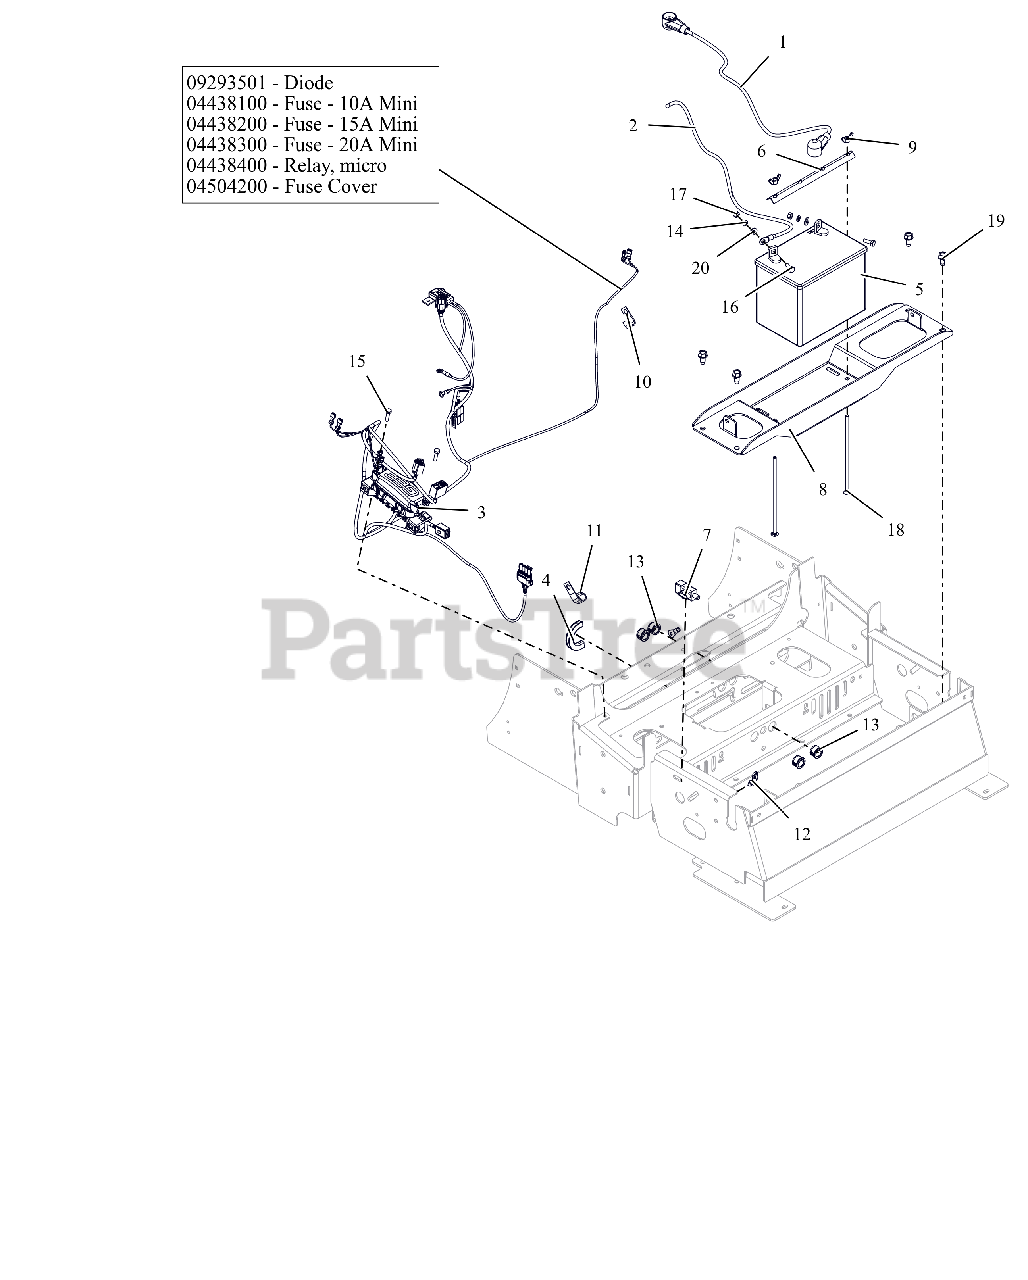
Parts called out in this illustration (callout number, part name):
1	CABLE - POS BATT W/BOOTS 6X35
2	CABLE-NEGATIVE BATTERY 35.00"
3	HARNESS, PT400 WIRING
3	DIODE, CONNECTOR SHELL
3	FUSE,10 AMP MINI-ATC
3	FUSE,15 AMP MINI-ATC
3	FUSE,20 AMP MINI ATC
3	RELAY,MICRO5 TERML W/RESISTOR
3	COVER, HARNESS FUSE/RELAY MOD
4	STRIP, COWL
5	BATTERY, 300 CCA 10U1L
6	HOLD DOWN
7	SWITCH, SNAP IN - N.O./N.O.
8	PT400 GAS BATTERY TRAY - RED
9	NUT, LK-WING .25-20 ZCC
12	CABLE TIE W/ TREE (.25 HOLE)
13	BUSH, PANEL SNAP .687X.875X.56
14	WSHR,LK-REG .250X.062 ZCC
15	BLT, HEX M6-1.0 X 25 G8.8 ZCC
16	BLT, HEX .25-20X.75 G5 ZCC
17	NUT-STD .250-20 G2 ZCC
18	BTL,RHSN .250-20 X 7.5 G5 ZCC
19	SCR,TAP .375-16X.75 HWH TR ZCC
20	WSHR,FLT .281X.625X.065 ZCC
